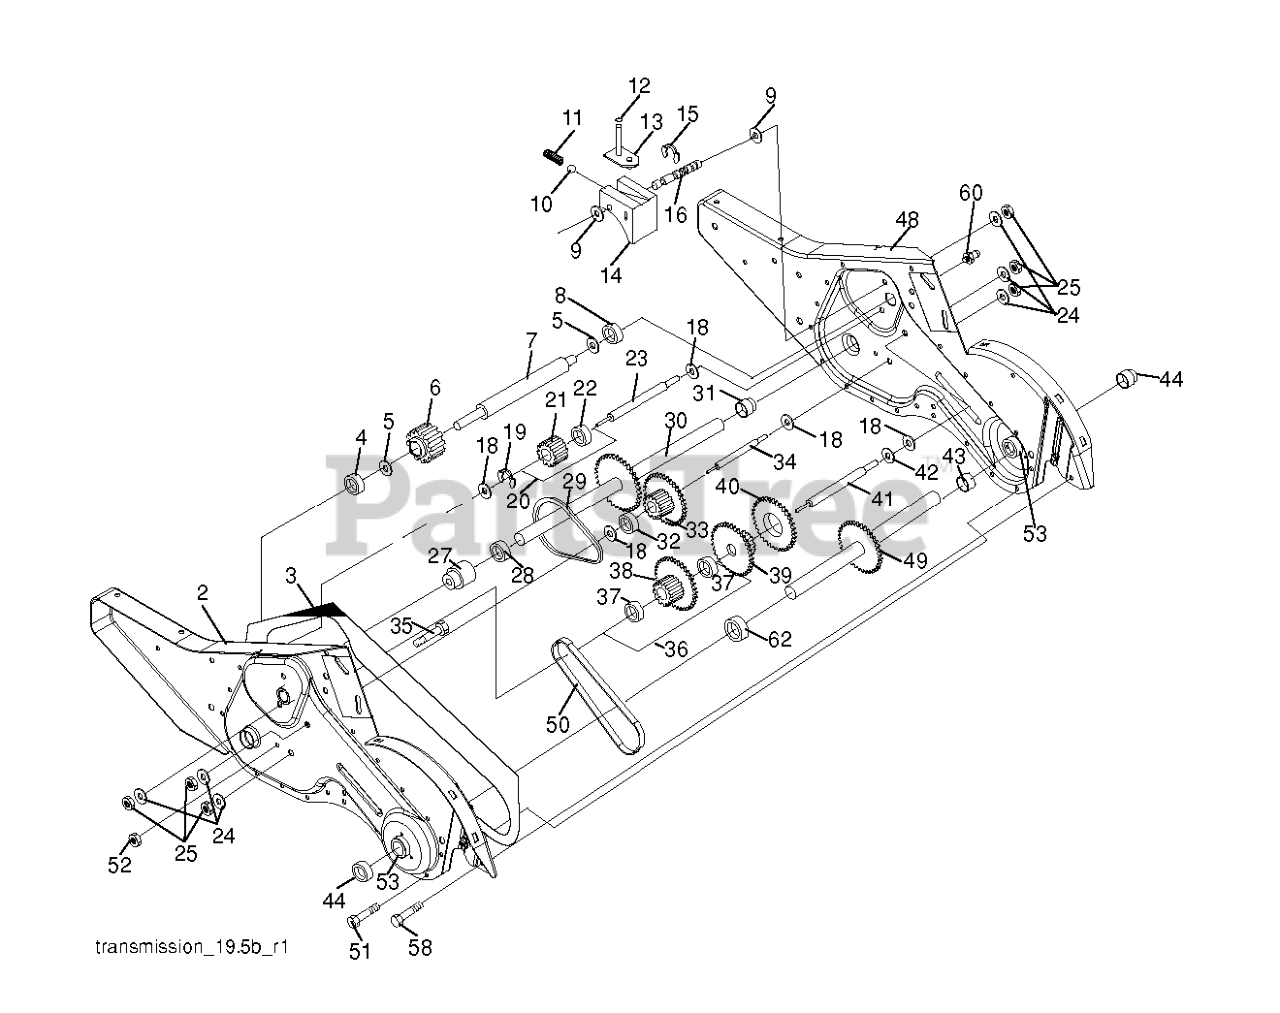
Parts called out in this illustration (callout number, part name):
1	TRANSMISSION ASM.
2	GEARCASE.ASM.CRT.LH.W/BEARING
3	GASKET.GEARCASE.CRT/DRT.TILLER
4	NEEDLE BRNG LT
5	THRUST WASHER
6	GEAR.PINION.INPUT
7	SHAFT.INPUT."D".TILLER
8	BEARING TI
9	WASHER, SEAL (2 2)
10	STEEL BALL KIT
11	SPRING-SHIFT CRT
13	BRACKET ASM.SHIFT.CRT
14	SHIFT FORK TI
16	SHAFT.SHIFTER.TILLER
20	GEAR ASSY CRT
21	GEAR-REV IDLR CRT
22	NEEDLE BEARING TI
24	LOCKWASHER
25	NUT.ASF.HEX.7/16
27	BEARING, SHAFT LH CRT
30	GROUND SHAFT ASS'Y
31	BEARING, SHAFT RH CRT
33	SPRCKT 8 GEAR CRT
34	SHAFT.SECONDARY.REDUCTION.CRT
35	SCRW WHIZ LOK CRT
36	SPROCKET.ASM.W/BEARING.TILLER
37	BEARING
38	SPROCKET, TINE
41	SHAFT.REDUCTION.TILLER
42	BRNG RACE T
44	SEAL ASM, OIL
48	GEARCASE.ASM.CRT.RH.W/BEARING
49	SHAFT.ASM.TINE
50	CHAIN.TILLER
51	SCREW
52	NUT
53	KIT.BEARING.TILLER.
58	BOLT SHOULDER 1/4-20 UNC X.875
60	FITTING.GREASE.TAPERED
62	SPACER.1.015X1.50X.650
